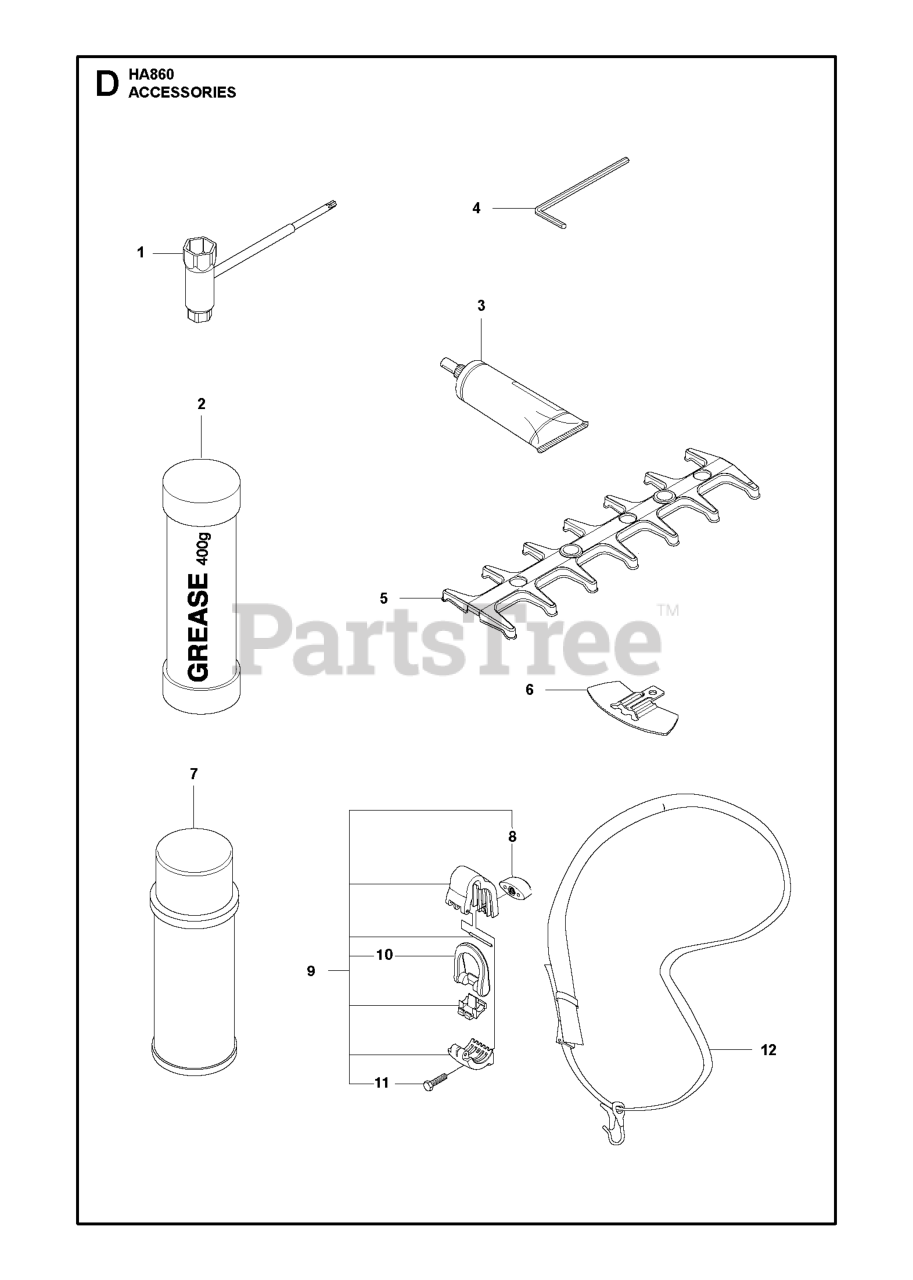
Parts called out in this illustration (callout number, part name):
1	COMBINATION WRENCH TORX
2	HUS MULTI ADVANCE GREASE 400GR
3	GREASE AS ACCESSORY
5	Protection
6	PROTECTION BLADE TIP
9	HANGING BRACKET
11	SCREW M6S 5X20
12	Harness-w/o warning
